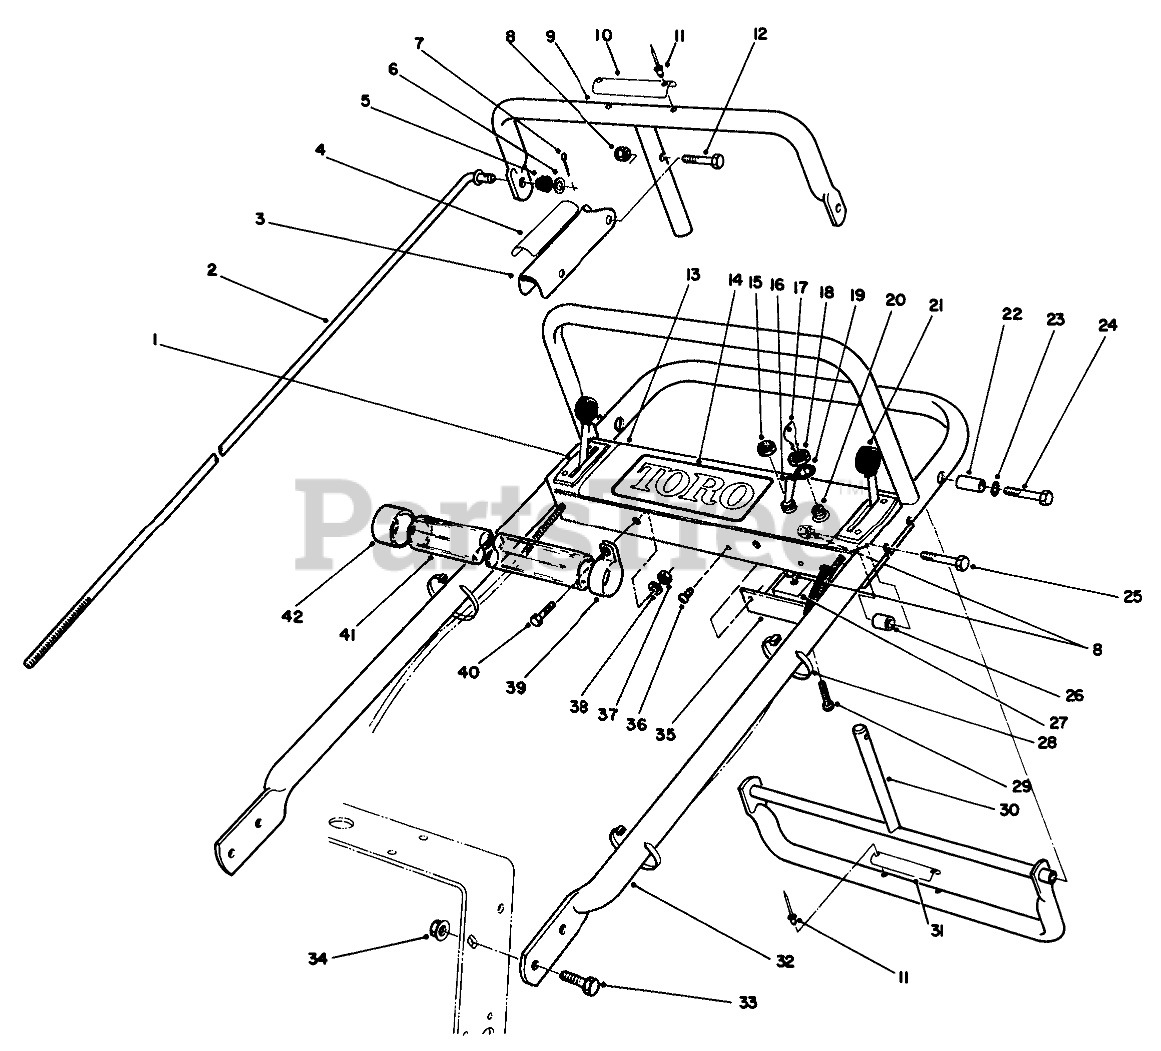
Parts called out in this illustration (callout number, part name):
1	CHOKE CONTROL
2	ROD-CONTROL
3	Lever-Parking Brake
4	DECAL-LEVER, PARKING
5	GROMMET-RUBBER
6	WASHER-PLAIN
7	PIN-COTTER
8	NUT-LOCK, NI
9	Bar-Control
10	DECAL-CONTROL BAR
11	RIVET-BLIND
12	SCREW-SHH
13	Panel-Control
14	RECOIL PANEL DECAL
15	NUT
16	Switch (Clutch)(Incl. Ref. #15)
17	KEY-IGNITION
18	NUT-HH
19	WASHER-TOOTH, INTERNAL
20	lgnition Switch (Incl. Ref. #17-19)
21	THROTTLE CONTROL
22	PIVOT-SPACER
23	WASHER-LOCK
24	SCREW-HH
25	SCREW-SHH
26	SPACER
27	RECTIFIER-BRIDGE
28	TIE-CABLE
29	SCREW-HWH
30	Control-Pivot
31	DECAL-REVERSE HANDLE
32	HANDLE-UPPER
33	SCREW-HHF
34	NUT-HF
35	PANEL-BOTTOM
36	SCREW-HWHTF
37	NUT-LOCK, NI
38	WASHER-FLAT
39	CLAMP-R
40	SCREW-HH
42	CAP-END
